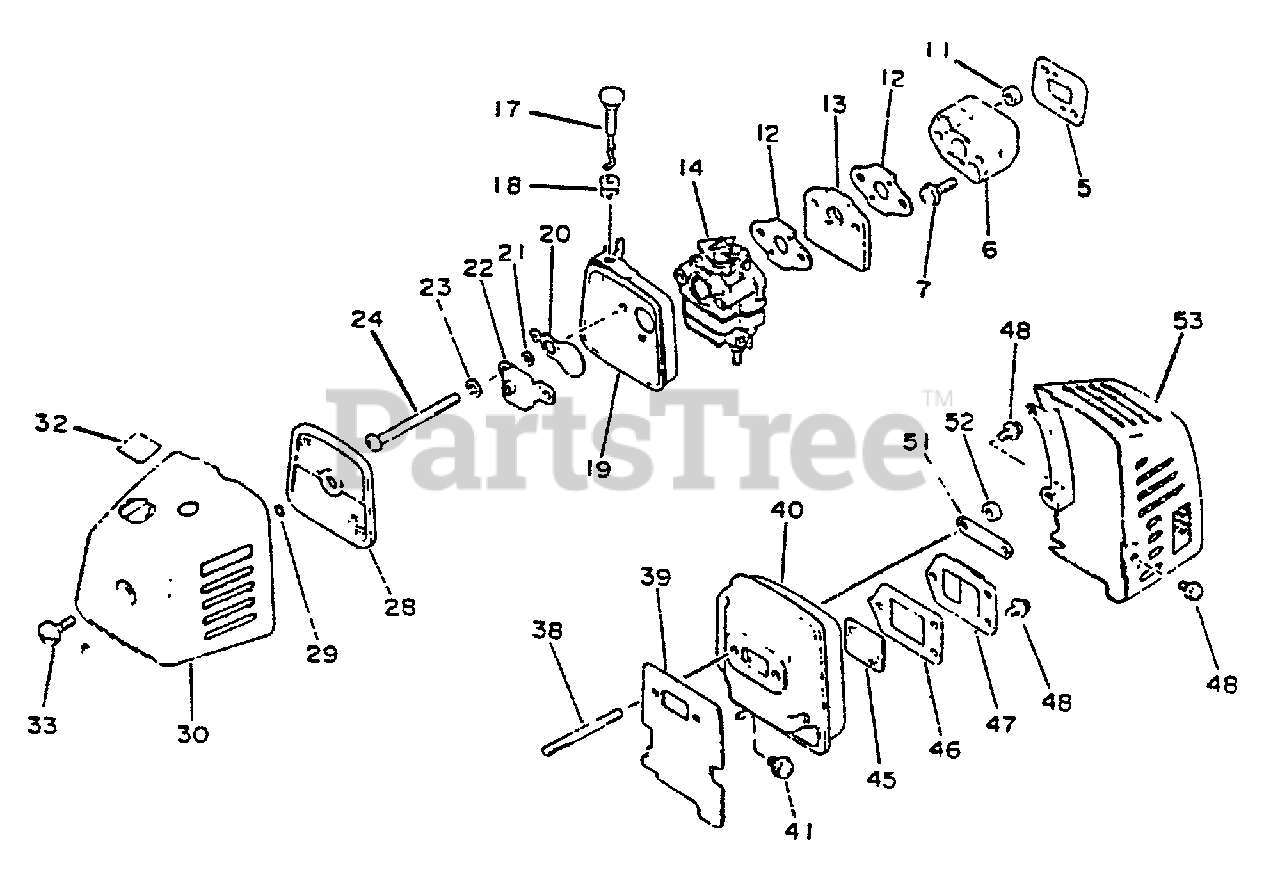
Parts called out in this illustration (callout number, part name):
5	GASKET, INTAKE
6	INSULATOR
7	SCREW 5×20
11	NUT M5
12	GASKET, INTAKE
14	CARBURETOR - WY-18
17	ROD, CHOKE
18	GROMMET, CHOKE
19	CASE, AIR FILTER
20	SHUTTER, CHOKE
21	WASHER 5.2×8×0.8T
23	WASHER, SPRING 5
24	SCREW 5×60
28	FILTER, AIR
30	AIR FILTER COVER ASSY
32	LABEL, CHOKE
38	BOLT, STUD
39	GASKET, EXHAUST
41	SCREW 5×10
45	SCREEN, SPARK ARRESTER
46	SCREEN, SPARK ARRESTER
47	LID, MUFFLER
48	SCREW 4×10
52	LOCKNUT - 5
53	COVER, EXHAUST
